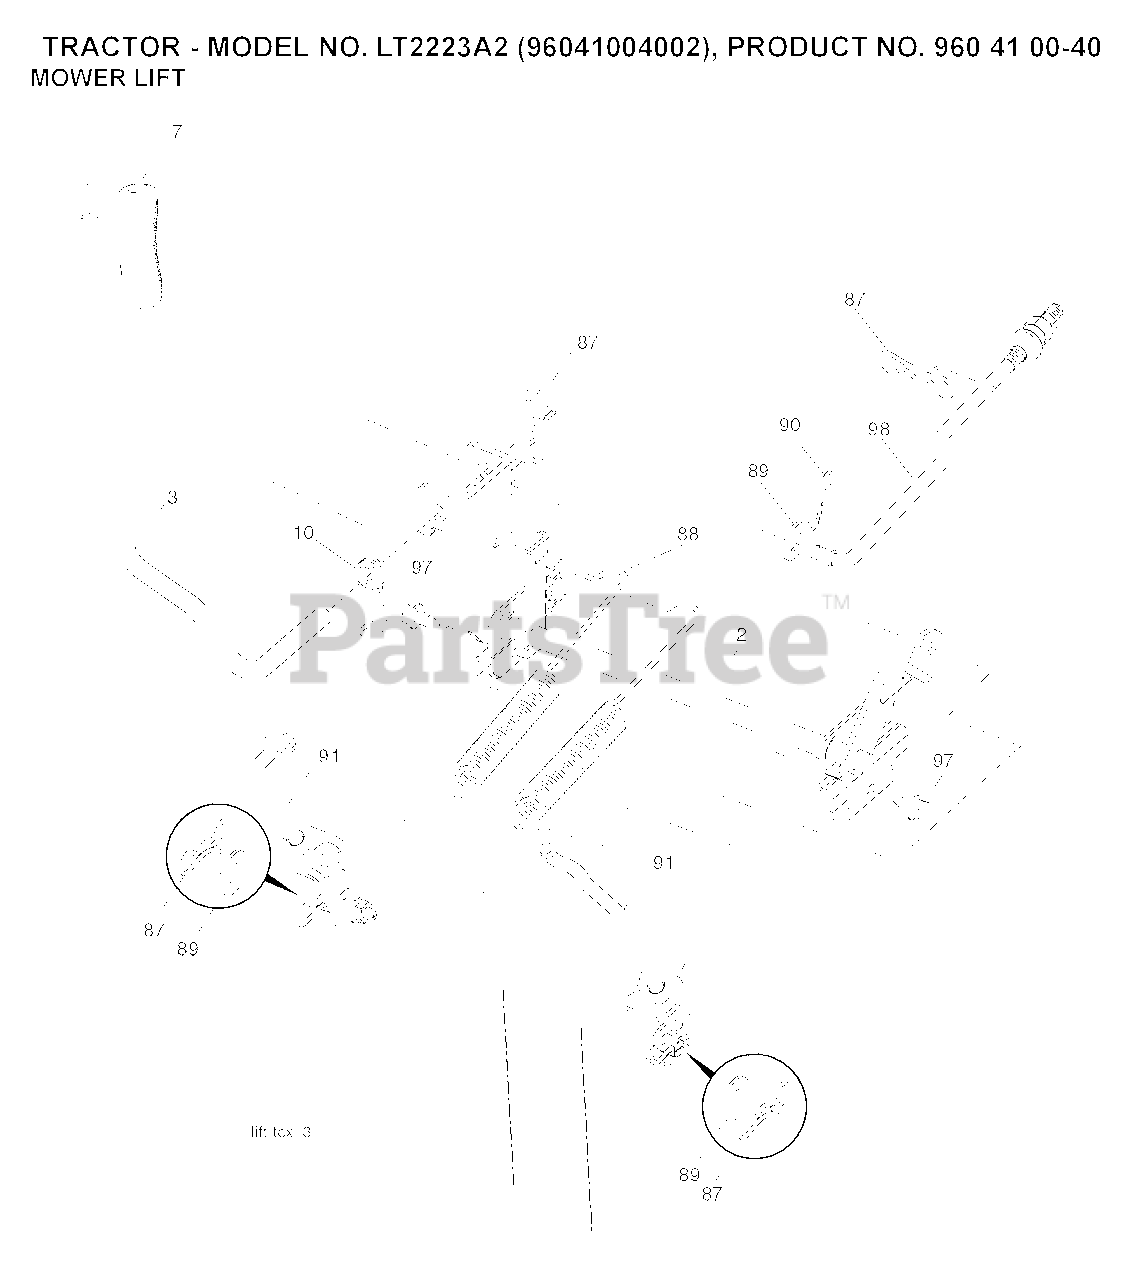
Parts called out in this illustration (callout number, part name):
2	SHAFT.ASM.LIFT.CROSS.H
3	LEVER.LIFT.HANDLE.GT
7	GRIP.HANDLE.LIFT.PVC.BLACK
10	SPRING.TORSION.LIFT.HANDLE
87	PIN.COTTER.7/16.BOW TI
88	SPRING.LIFT.ASSIST.GT2
89	WASHER.CLEAR.ZINC
90	PIN.COTTER.5/16.BOW TI
91	LINK.ASM.LIFT.REAR
97	SCREW, 3/8-16X3/4
98	LINK.ASM.SUSP.FRONT.MW
100	LOCKNUT
